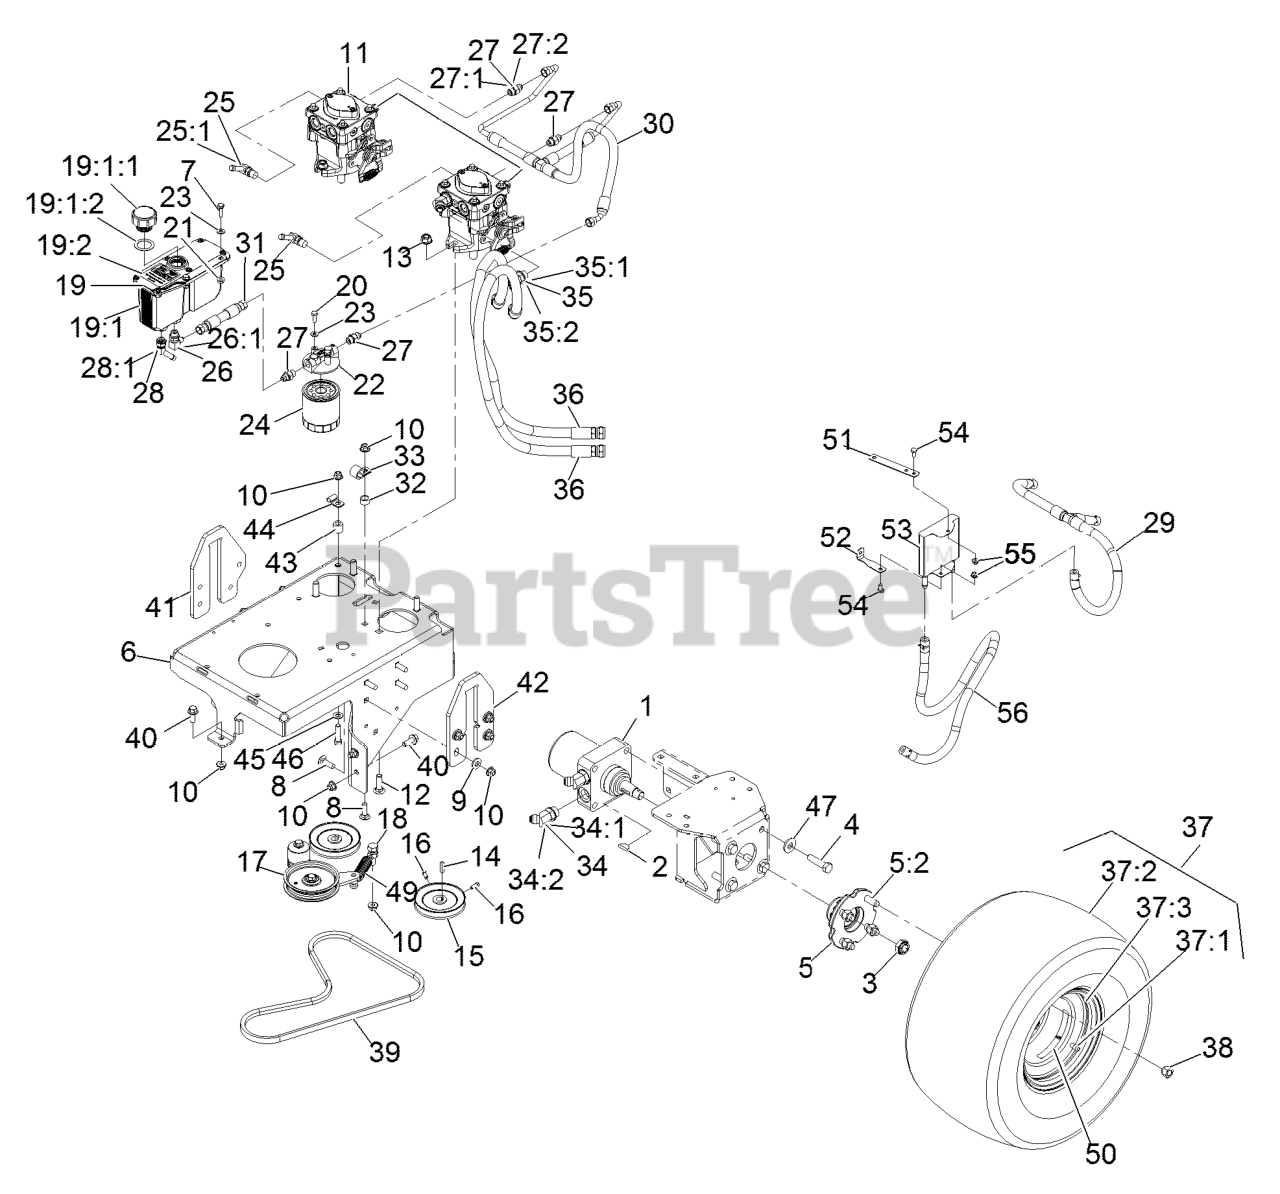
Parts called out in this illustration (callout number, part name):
1	MOTOR-WHEEL
2	KEY-WOODRUFF
3	NUT-LOCK
4	SCREW-HH
5	WHEEL HUB ASM
5:2	STUD-TYPE, DRIVE
6	BASE-ENGINE
7	SCREW-HH
8	BOLT-CARR
9	WASHER-BELLEVILLE
10	NUT-HF, NI
11	PUMP - HYDRAULIC
12	SCREW-HH
13	NUT-HF, NI
15	PULLEY-PUMP
16	SCREW-SET
17	PUMP IDLER ASM
19	RESERVOIR ASM
19:1	Reservoir-Hyd
19:1:1	Cap-Reservoir, HYD
19:1:2	GASKET-CAP
19:2	DECAL-HYDRAULIC TANK
20	SCREW-HH
21	NUT-HHF
22	HEAD-FILTER
23	WASHER-FLAT
24	FILTER-25 MICRON, BI-DIRE
25	FITTING-ELBOW, 90
25:1	O-RING
26	FITTING-ELBOW, 90 DEG
27	FITTING-STRAIGHT
28	FITTING-BARBED, 45 DEG
28:1	O-RING
29	HOSE ASM-CASE DRAIN
30	HOSE ASSEMBLY - CHARGE
31	HYD HOSE ASM
32	SPACER-WHEEL
33	CLIP-LOOM
34	FITTING-HYD, 45 DEG
35	FITTING-HYD, 45 DEG
36	HYD HOSE ASM
37	WHEEL/TIRE ASM
37:1	RIM-8 INCH
37:3	Stem-Valve
38	NUT-LUG
39	BELT-V, LOWER PTO
40	SCREW-HHF 3/8-16 X 1
41	PLATE-LIFT, RH
42	PLATE, LIFT LH
44	CLIP-TUBE
45	WASHER-FLAT
46	SCREW-HH
47	WASHER-SPRING
49	SPRING-EXTENSION
51	BRKT-COOLER MOUNT, TOP
52	BRKT-COOLER MOUNT, BOTTOM
53	COOLER-OIL
54	SCREW-HH
56	HOSE ASM
